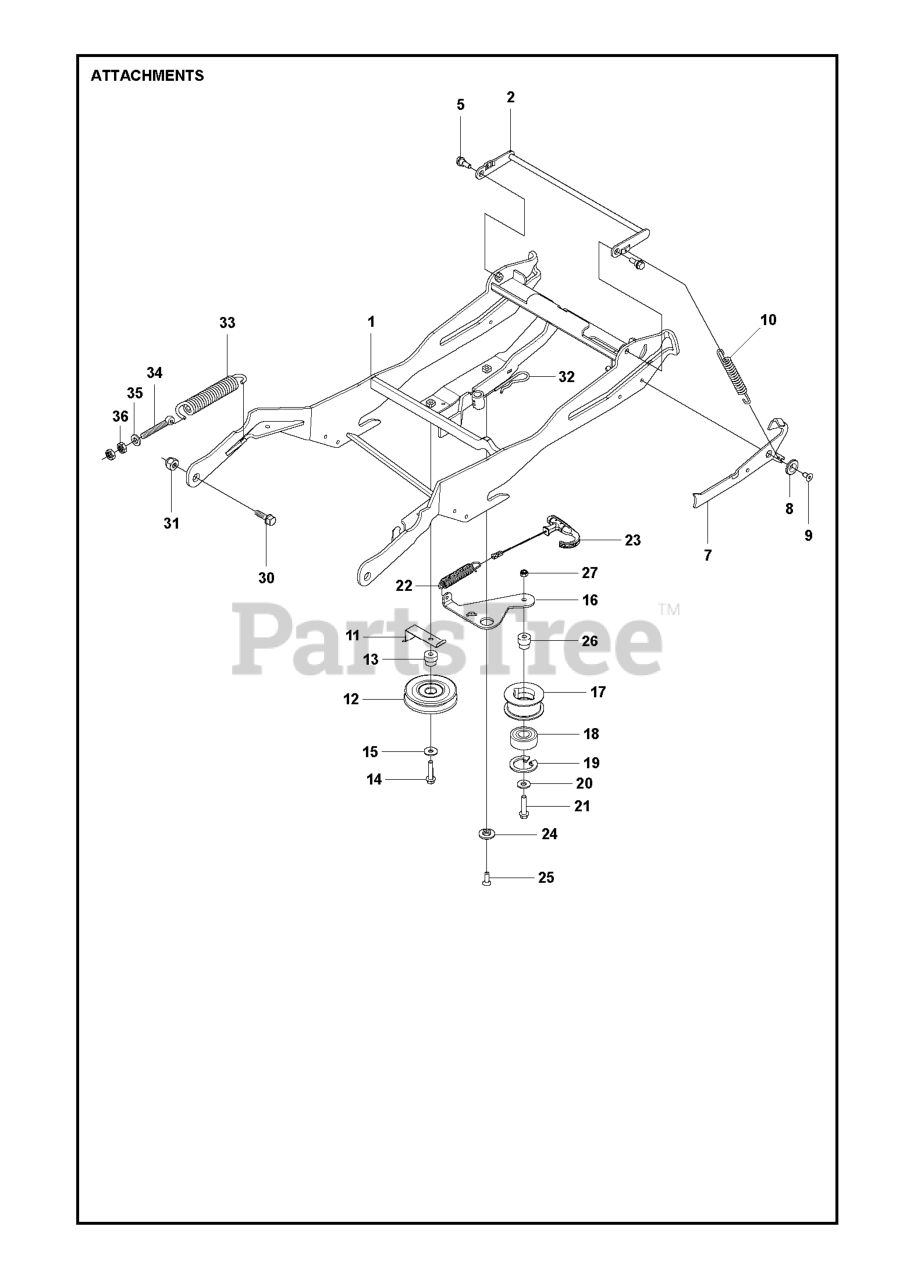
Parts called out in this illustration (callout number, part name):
1	EQUIPMENT FRAME
8	SPACER
9	SCREW IHCSFM
11	BELT GUIDE
17	BELT TENSIONER WHEEL ASSY
18	BALL BEARING 6004-2RS1
19	RETAINING RING
23	HANDLE ASSY
24	WASHER
27	LOCKNUT M8
35	WASHER
